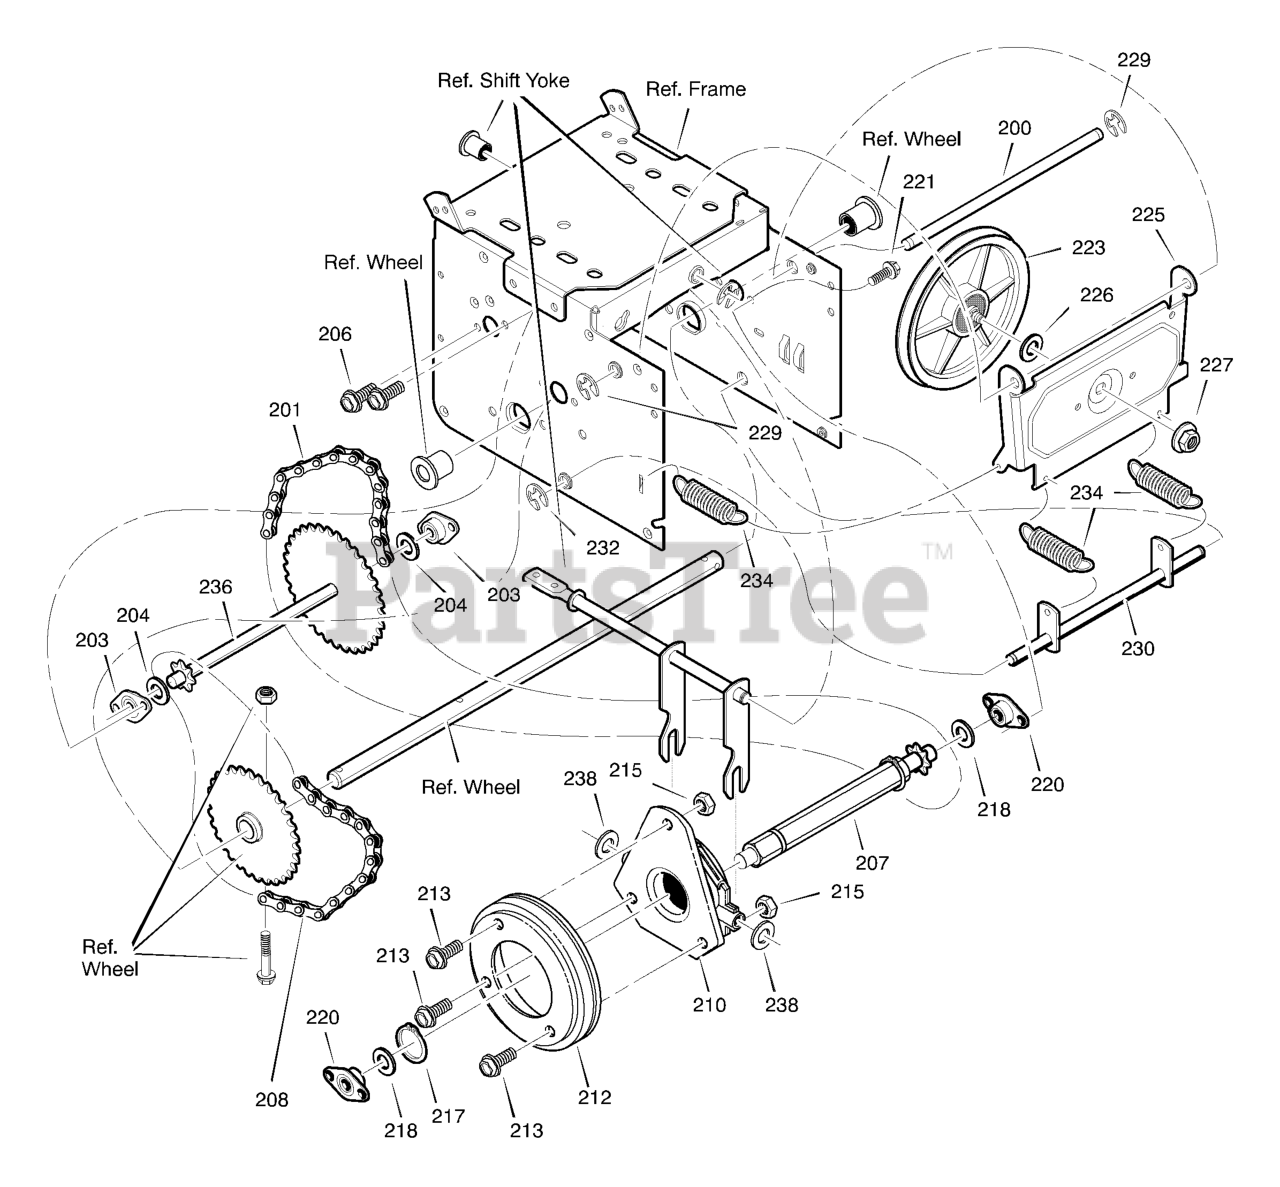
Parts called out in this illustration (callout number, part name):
200	LF AXLE, SWING PLATE YZ
201	CHAIN, ROLLER #42x19.00 LG
203	BEARING AND RETAINER, ASSY
206	SCREW, TAP 5/16--18x0.5
207	ASSY, HEX SHAFT
208	CHAIN, ROLLER #36x18.00 LG
210	BEARING, TRUNION CLUTCH R
212	WHEEL, FRICTION DISC
213	SCREW, 1/4--20 x 0.63
215	NUT, KEPS HEX 1/4--20
217	RING, RETEXT
220	BEARING AND RETAINER, ASSY
221	SCREW, TAP 5/16--18 x .5
223	ASSY, FRICTION PULLEY
225	LF PLATE, SWINGING YZ
226	SPACER, FRICTION PULLEY
227	NUT, FLANGE LOCK 3/8--24
229	RETAINER, RING
230	LF ASSY, SPRING LINK YZ
232	RETAINER, RING
234	SPRING, EXTENSION
236	WLD, INTERMED SPROCKET 33T/7
238	WASHER, FLAT
